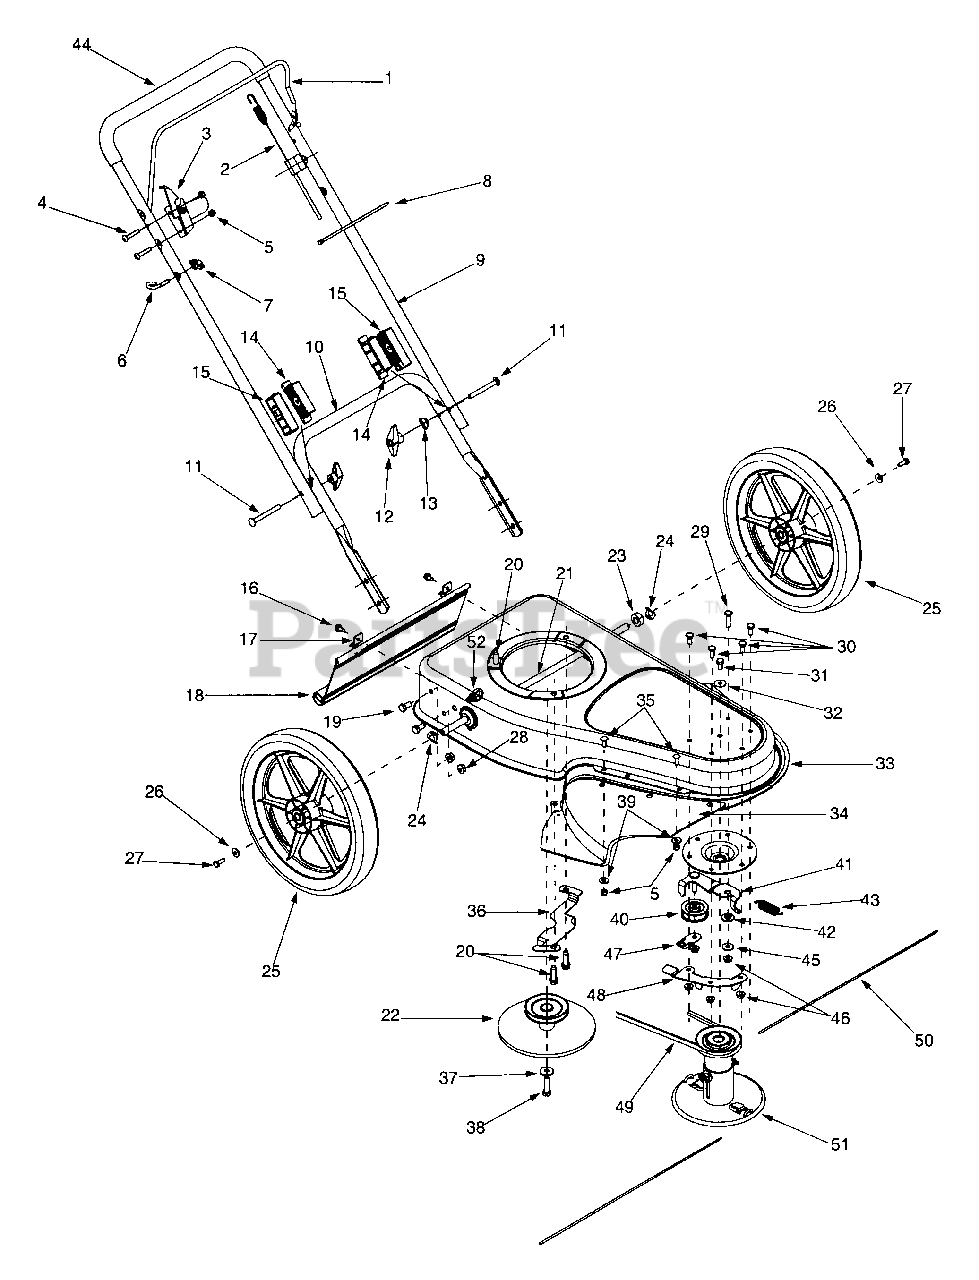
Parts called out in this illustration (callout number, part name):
2	Engagement Cable
3	Control Lock Bracket
4	Machine Screw 1/4-20 x 1.50
5	Hex Lock Nut 1/4-20
6	Eye Bolt 1/4-20
7	Wing Nut
8	Cable Tie
12	Wing Nut
13	Shoulder Washer.320 ID x .93 OD
14	Lower Handle Connector
15	Upper Handle Connector
16	Hex Washer Screw 1/4-14 x 625
17	Trail Shield Clip
18	Trail Shield
19	Hex Cap Screw 3/8-16 x .750
20	Hex Washer Screw 3/8-16 x 1.25
21	Trimmer Axle
22	Flywheel Pulley
23	Spacer.51 ID x 1.0 OD
24	Spacer Washer .501 ID x 1.0 OD
25	Wheel Assembly
26	Bell Washer.265 ID x .75 OD
27	Hex Cap Screw 1/4-20 x 75
28	Flange Lock Nut 3/8-16
29	Screw 5/16-18 x 1.25
30	Screw 5/16-18 x 75
31	Hex Cap Screw 5/16-24 x 625
32	Bell Washer 325 ID x .930 OD
35	Hex Carriage Screw 1/4-20 x 75
38	Hex Cap Screw 3/8-24 x 1.50
39	Flat Washer 28 ID x 74 OD
40	Idler Pulley
41	Idler Bracket Assembly
42	Idler Spacer
43	Extension Spring 50 Dia x 1.88 Lg
44	Handle Grip
45	Flat Washer
46	Flange Lock Nut 5/16-18
49	V-Belt
50	Trimmer Line 155 Dia
51	Spindle Assembly, includes 782-0143
52	Cable Retainer Clip
